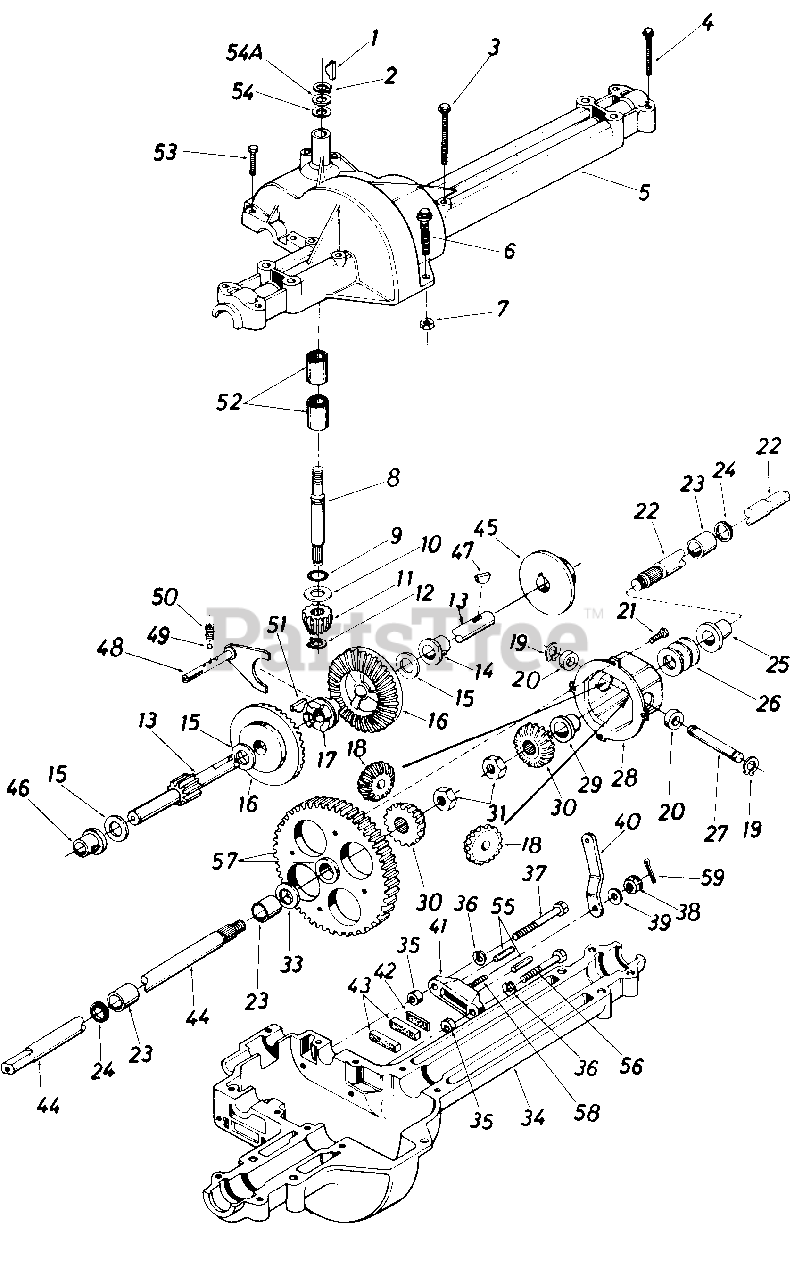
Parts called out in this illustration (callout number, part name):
1	#4 Hi-Pro Key 3/32 x 518" Dia.
2	Snap Ring .625" Shaft
3	Hex Bolt 1/4-20 x 1.75" Lg.
4	Hex Bolt 1/4-20 x 1.25" Lg.
5	Upper Housing
6	Hex Fl-Bolt 1/4-20 x .88" Lg.
7	Hex Nut 1/4-20 Thd.
8	Input Shaft
9	Square Seal 5/8" I.D.
10	Thrust Washer 5/8" I.D. x 1.25" O.D.
11	Pinion Input 14T
12	Retaining Ring 7/16" Ext.
13	Drive Shaft R.H.
14	Flange Brg. 5/8" I.D. x 3/4" Lg.
15	Fl-Wash.
16	Bevel Gear 42T
17	Clutch Collar
18	Miter Gear 15T H.D.
19	Snap Ring
20	Thrust Bearing 1/2" I.D. x 1.0" O.D.
21	Pan Head Scr. 1/4-20 x .50" Lg. w/Patch
22	Axle R.H.
23	Sleeve Bearing 3/4" I.D. x 1.0" Lg.
24	Oil Seal 3/4" I.D.
25	Flange Bearing 3/4" I.D. x 15/16" Lg.
26	Fl-Wash. .760" I.D. x 1.49" O.D.
27	Cross Shaft
28	Differential Housing Ass'y.
30	Miter Gear H.D.
31	Hex Ins. L-Nut 1/2-20 Thd.
33	Fl-Wash. .760" I.D. x 1.49" O.D.
34	Lower Housing
35	Spacer .53" O.D. x 3/8" Lg.
36	L-Wash. 1/4" I.D.
37	Hex Bolt 1/4-20 x 1.50" Lg. (Grade 5)
38	Castle Nut 5/16-24 Thd.
39	Fl-Wash. .344" I.D. x .875" O.D.
40	Actuating Arm R.H.
41	Brake Yoke
42	Puck Plate
43	Brake Puck
44	Axle L.H.
45	Brake Disc
46	Flange Bearing 518" I.D. x 15/16" Lg.
47	Woodruff Key 3/16 x 5/8 HT
48	Shift Fork Ass'y.
49	Ball Detent .250" Dia.
50	Spring Detent
51	#9 Hi-Pro Key 3116" x 3/4" Dia. HT
52	Needle Brg. 518" I.D. x 1/2" Lg.
53	Hex Bolt 1/4-20 x 1.00" Lg.
54	Fl-Wash. 518" I.D. x .030
54A	Fl-Wash. 518" I.D. x .040
55	Actuating Pin 5/16" Dia.
56	Hex Bolt 1/4-20 x 1.50" Lg. (Grade 5)
57	Differential Gear 72T Ass'y. w/Bearing
58	Sq. Hd. Bolt 5/16-24 Thd.
59	Cotter Pin 3132" Dia. x .50" Lg.
